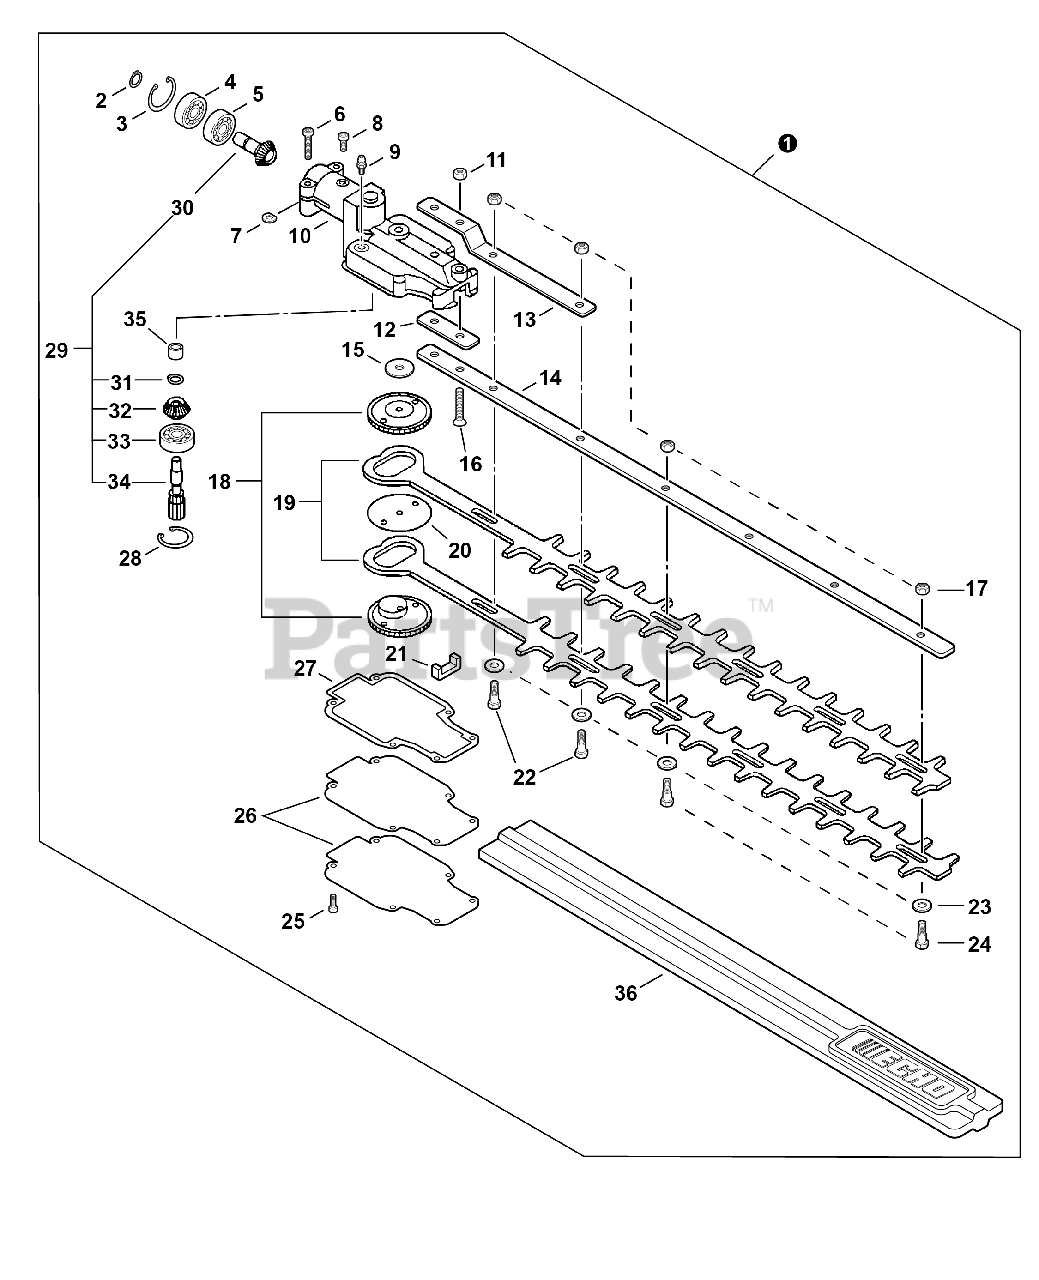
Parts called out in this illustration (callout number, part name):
1	GEAR CASE ASSY
2	RING, RETAINING - 12
3	RING, RETAINING - 24
4	BEARING, BALL - 6901Z
5	BEARING, BALL - 6901
6	SCREW - 5×28
7	WASHER, SHIM
8	SCREW - 5×12
9	FITTING, GREASE
10	CASE, GEAR - UPPER
11	LOCKNUT - 6
12	PLATE, EYE
13	BRACKET, BLADE
14	SUPPORT, BLADE
16	SCREW - 6×35
17	LOCKNUT - 6
18	GEAR, SPUR
19	BLADE, TRIMMER
21	SEAL, FELT
23	WASHER - 6
24	BOLT - 6
25	SCREW - 4×12
26	LID, GEAR CASE
27	GASKET, GEAR CASE
28	RING, RETAINING - 24
29	SPUR GEAR SET
30	GEAR, BEVEL
31	RING, RETAINING
32	GEAR, BEVEL
33	BEARING, BALL - 6901
34	GEAR, SHAFT
35	BEARING, NEEDLE
36	COVER, BLADE
